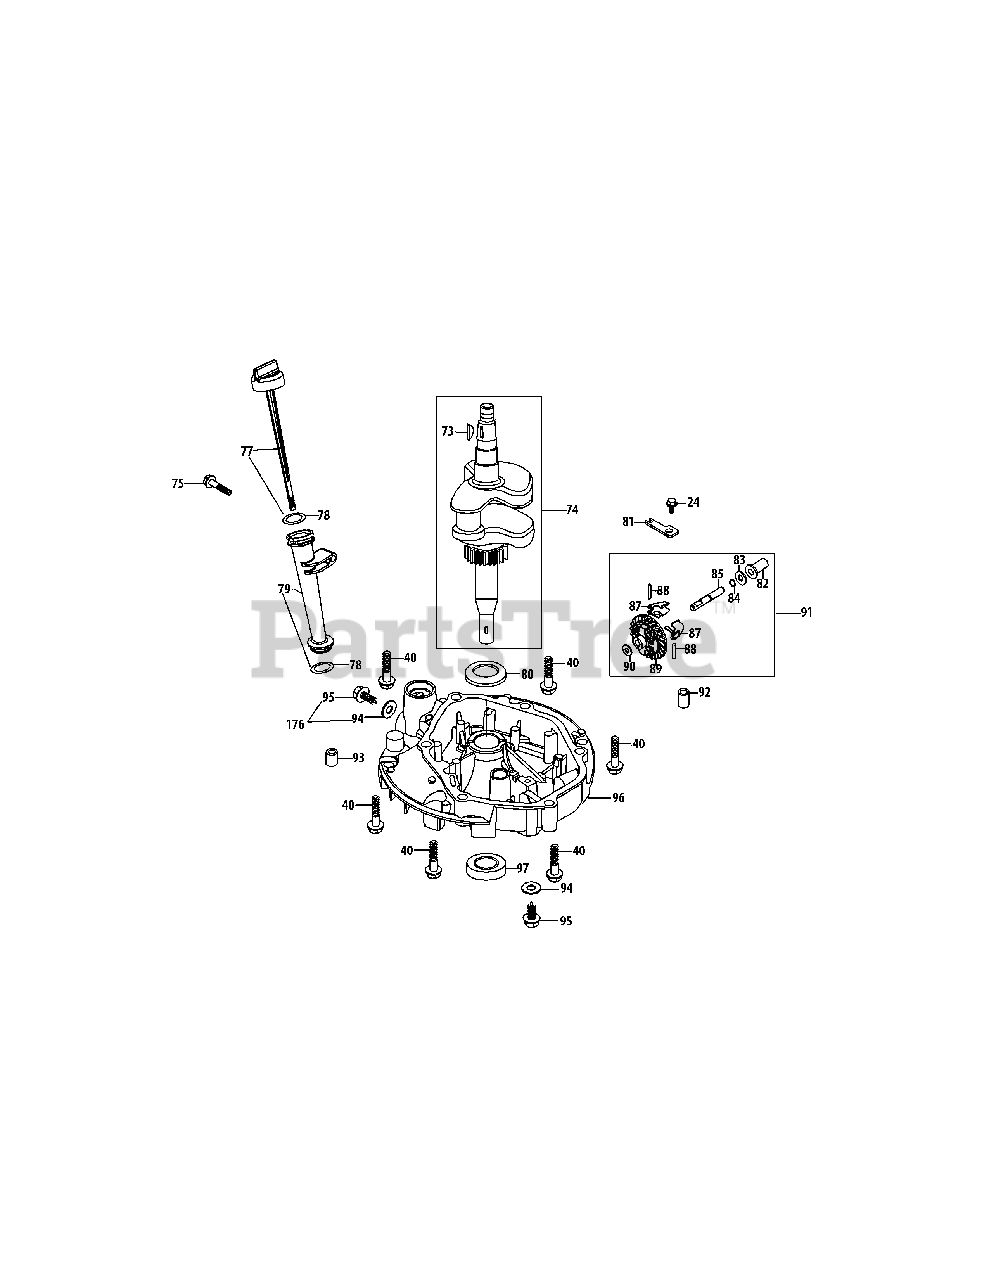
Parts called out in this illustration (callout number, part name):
24	Bolt M6×14
40	Bolt M8×50
73	Woodruff Key
74	Crankshaft Assembly
75	Bolt M6×35
77	Dipstick Asm
78	Dipstick / Oil Fill Tube O-Ring
79	Oil Fill Tube Asm
80	Crankshaft Thrust Washer
81	Governor Gear Mounting Plate
82	Governor Slide Cap
83	Governor Slide Cap Washer
84	Governor Shaft Stop Ring
85	Governor Shaft
86	Governor Gear Assembly
87	Governor Fly Weight
88	Governor Fly Weight Pin
89	Governor Gear
90	Governor Gear Washer
91	Governor Gear / Shaft Assembly
92	Dowel Pin 7×14
93	Dowel Pin 9×14
94	Oil Drain Plug Washer
95	Oil Drain Plug
96	Crankcase Cover
97	Lower Crankshaft Seal
176	Oil Drain Plug and Washer Ass'y
